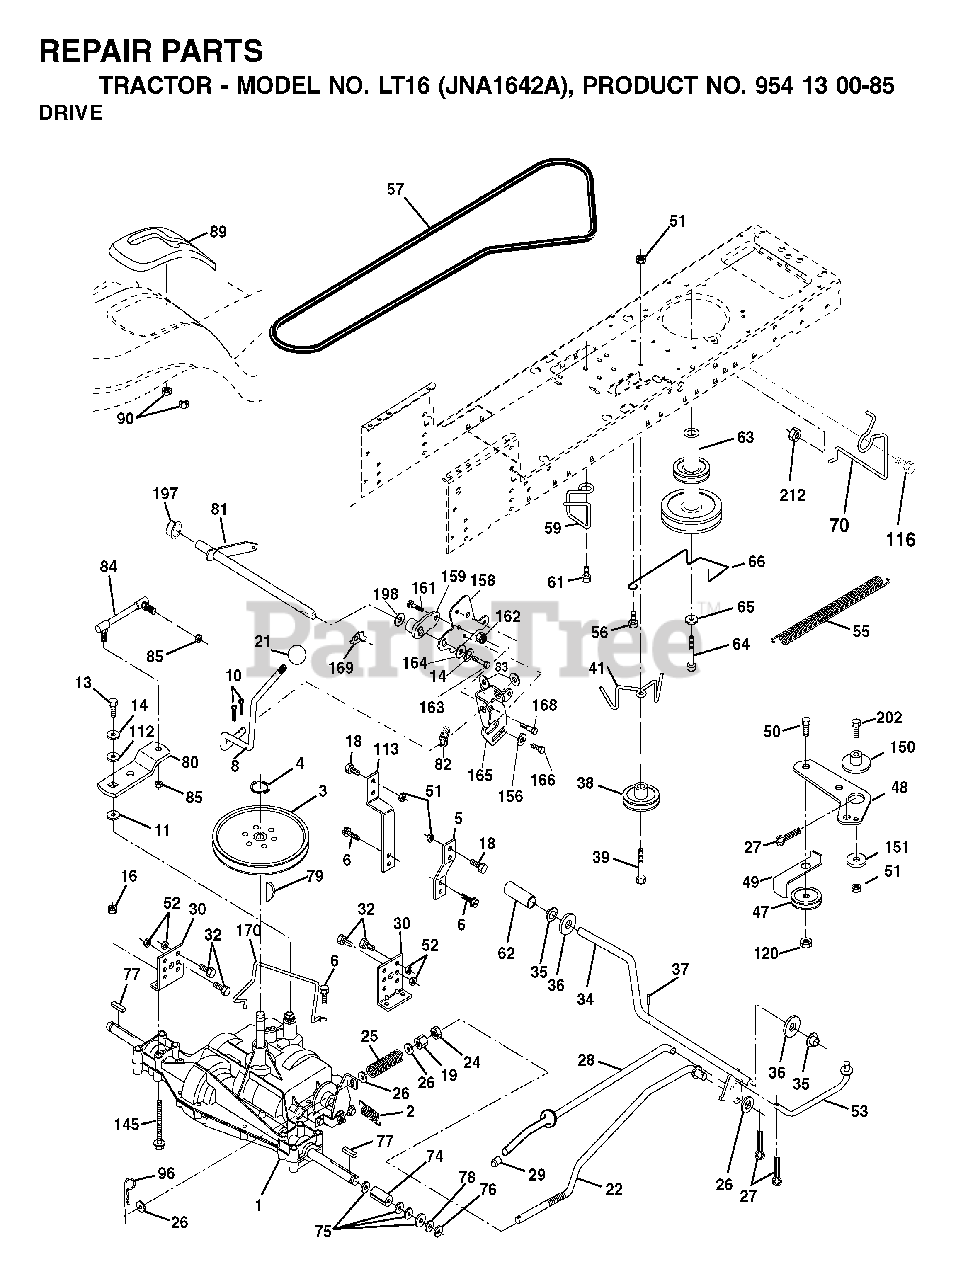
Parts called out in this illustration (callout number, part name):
2	SPRING,BRAKE RETURN
3	PULLEY TRANS
4	RETAINING RING LT
5	STRAP TORQUE
6	SCREW 5/16"
8	ROD SHIFT FENDER ADJUST STLT
10	PIN COTTER
11	WASH-SHFT PLT LT
13	BOLT 1/4-28X3/4
14	LOCKWASHER
16	NUT.71038.31-18.HEX.NYLOCK
19	NUT
21	PISTOL KNOB
22	ROD BRAKE
24	NUT
25	SPRING ROD LT
27	COTTER PIN
28	ROD, PARKING BRAKE
29	PLUNGER CAP
30	BRKT, TRNSXLE MNT 20"
32	BOLT
34	SHAFT, FOOT PEDAL
35	BEARING.NYLON
36	WASHER LT
37	DRIVE PIN
38	PULLEY IDLER COMPOSITE
39	BOLT
41	KEEPER, BELT IDLER
47	IDLER PULLEY
48	BELLCRANK, CLUTCH
49	RETAIN BELT
50	BOLT
51	LOCKNUT
52	LOCKNUT
53	LINK, CLUTCH LT
55	SPRING, RETURN LT
56	SCREW.3/8-16
57	V-BELT
59	KEEPER, BELT CENTER
61	SCREW 3/8-16X.875
62	PEDAL COVER T
63	ENGINE PULLEY
64	BOLT
65	LOCKWASHER
66	KEEPER BELT ENGINE
70	KEEPER BELT ENG
74	SPACER AXLE
76	E-RING LT
77	SQUARE KEY
80	ARM SHIFT
82	SHIFT SPRING
83	WASHER
85	NUT LOCK CENTER 1/4 -28 FNTHD
89	CONSOLE.SHIFT.STLT.6SP.BLACK
96	RETAINER M
112	WASHER LT
113	STRAP TORQUE LH LT
116	BOLT D
120	NUT LOCK FLG 3/8-16 UNC
150	SPACER, RETAINER
151	WASHER 12/32X2X10GA
156	WASHER.SRRTD.5/16
158	BRACKET
159	HUB
161	BOLT
162	NUT.CROWNLOCK.1/4
165	RP BRACKET
168	BOLT.SHOULDER.5/16-18X
169	PLATE.FASTENING.CROSS.SHAFT
170	KEEPER BELT T/A
197	NYLINER SNAP 5/8" ID
198	WASHER.NYL.7/8IDX.105"HYD CR
202	BOLT
212	NUT
